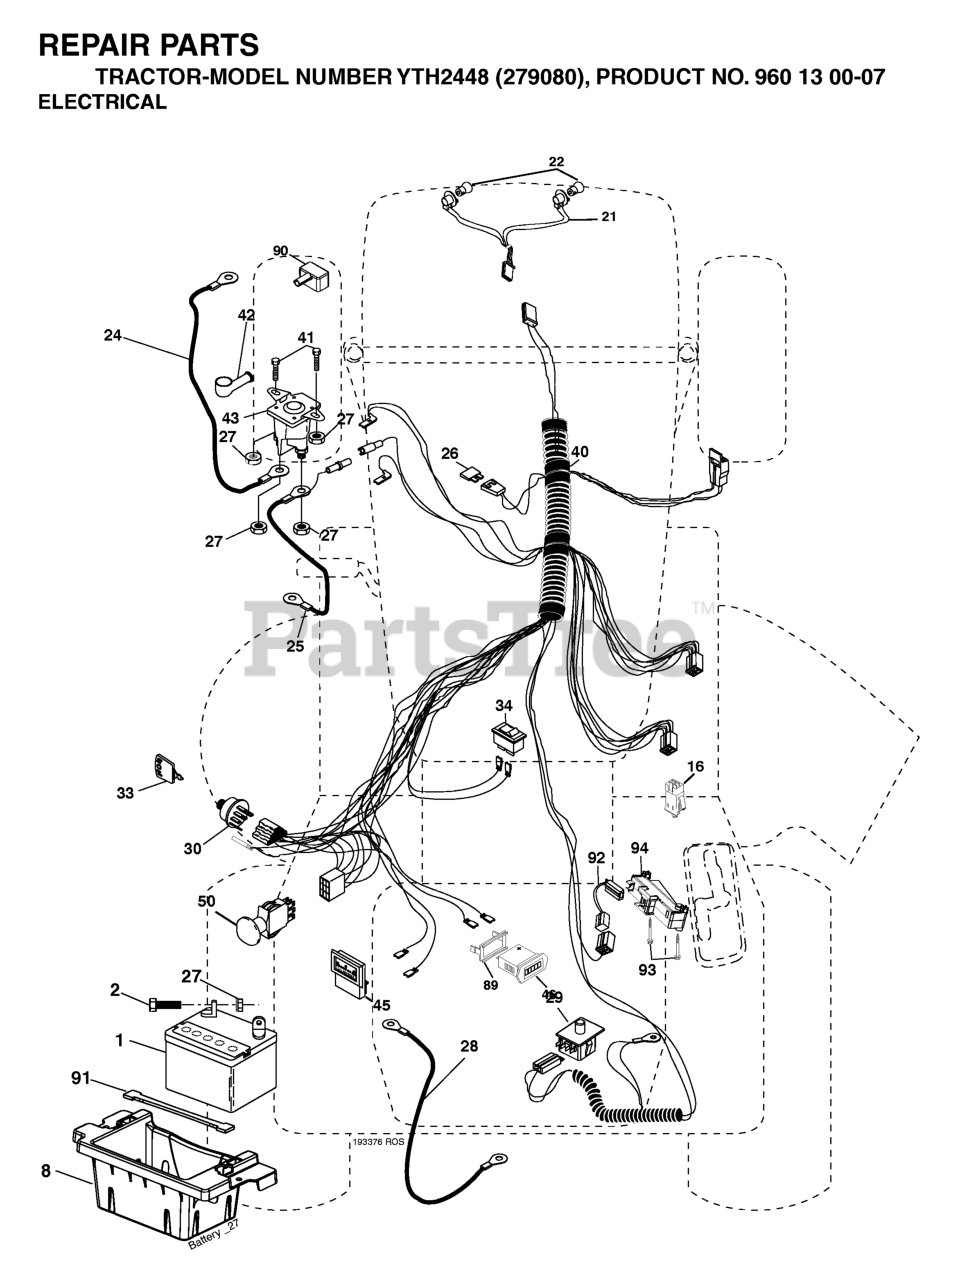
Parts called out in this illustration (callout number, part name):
1	BATTERY 12V .35 AMP
2	BOLT.HEX.1/4.X.3/4.DICHROMATE
8	BOX.BATTERY.MOUNT.FRONT.LT
16	SWITCH INTERLOOK PUSH-IN
21	HARNESS ASSY LIGHT
24	BATTERY CABLE GT
25	CABLE BATTERY 6 GA 22" W/16W
26	FUSE 20AMP
27	NUT
28	CABLE GROUND 6 GA 21" 90T BLK
29	SWITCH.SEAT.DP W/RAMPS
30	SWITCH.IGN.DELTA.W.LGH.ROS
33	KEY MLD GEN DELTA
40	HARNESS.IGN.ELECT.STL
41	BOLT
42	TERMINAL COVER
43	SOLENOID
46	HOUR METER
50	RP.PTO.SWITCH.8 TERMINAL.BLACK
55	Screw 5/16-18 x 1/2 Hex, Self Tapping 5/16-18 x 1/2
89	BRACKET SNAP-IN HOURMETER
90	COVER TERMINAL
91	STRAP.BATTERY.MOUNT.FRONT(2 2)
92	HARNESS.PIGTAIL.REVERSE.SWITCH
93	SCREW.PLASTITE
94	MODULE.REVERSE.ROS
